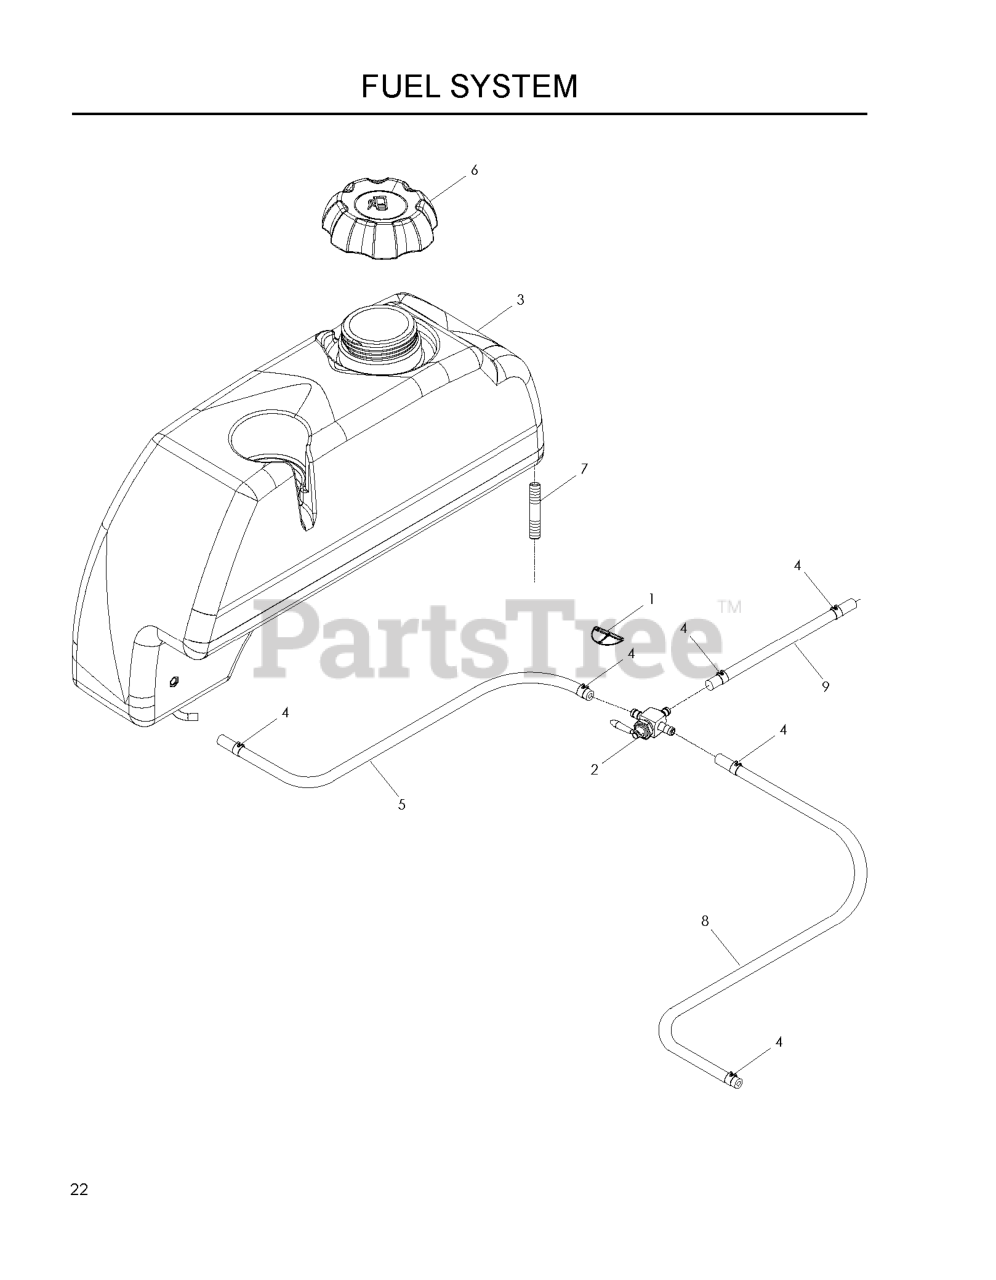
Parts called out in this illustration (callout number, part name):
1	DECAL, FUEL VALVE
2	FUEL VALVE
3	LEFT TANK W/CUP HOLDER
3	FUEL TANK RT
4	HOSE CLAMP
6	FUEL CAP ANTI-SPLASH
7	STUD, 5/16C
9	FUEL LINE 13"
